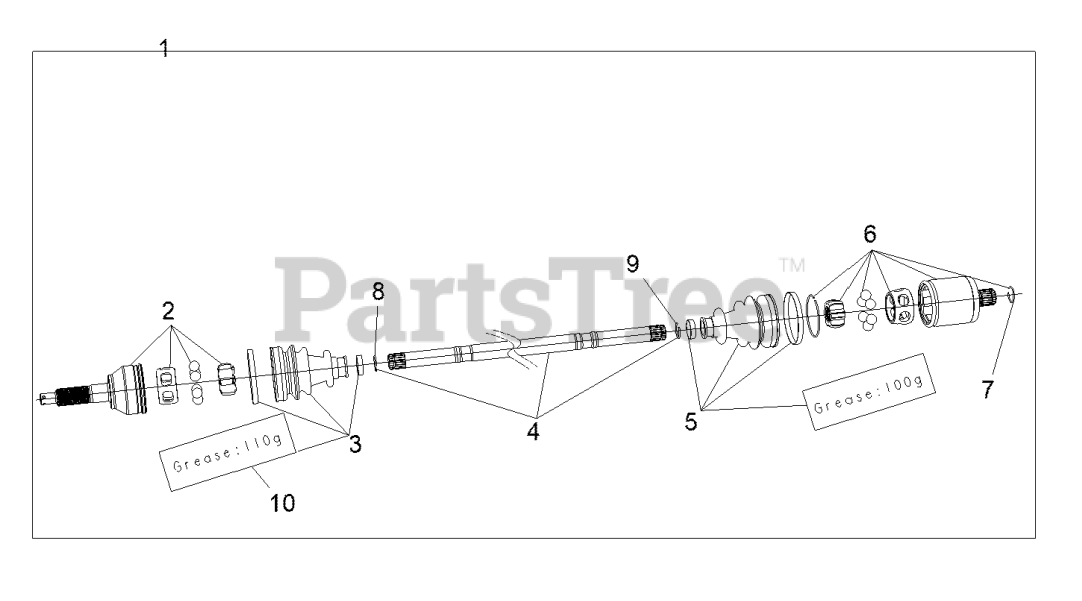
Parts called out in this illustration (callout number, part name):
1	ASM-HALFSHAFT-REAR
2	JOINT OUTER
3	KIT-BOOT(PR-8071)
4	BAR
5	K-BOOT- INNER
6	JOINT- INNER
10	GREASE(K575/VW738)
